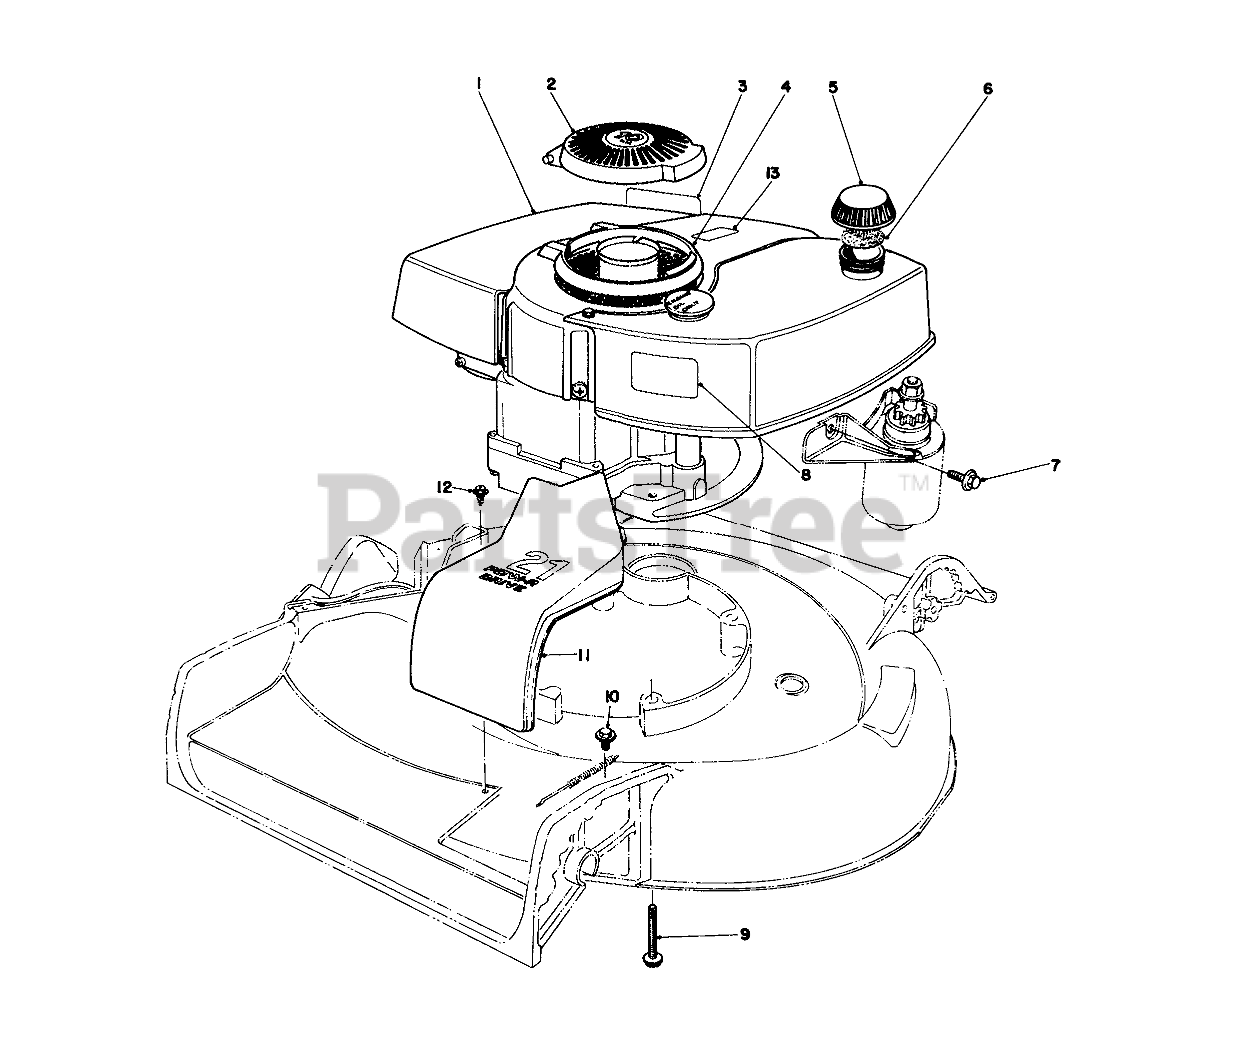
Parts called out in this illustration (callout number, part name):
1	Engine
2	Cover-Hinged
3	Decal Maintenance
4	Base Hinged
5	Gas Cap Assembly (Incl. Ref. #6)
6	GAS CAP GASKET
7	SCREW
8	Decal
9	3/8-16 X 2-3/4 CAPSCR
10	SCREW-HWHTF
11	Cover Belt Drive
12	SCREW-HWHTF
13	Decal-Caution
